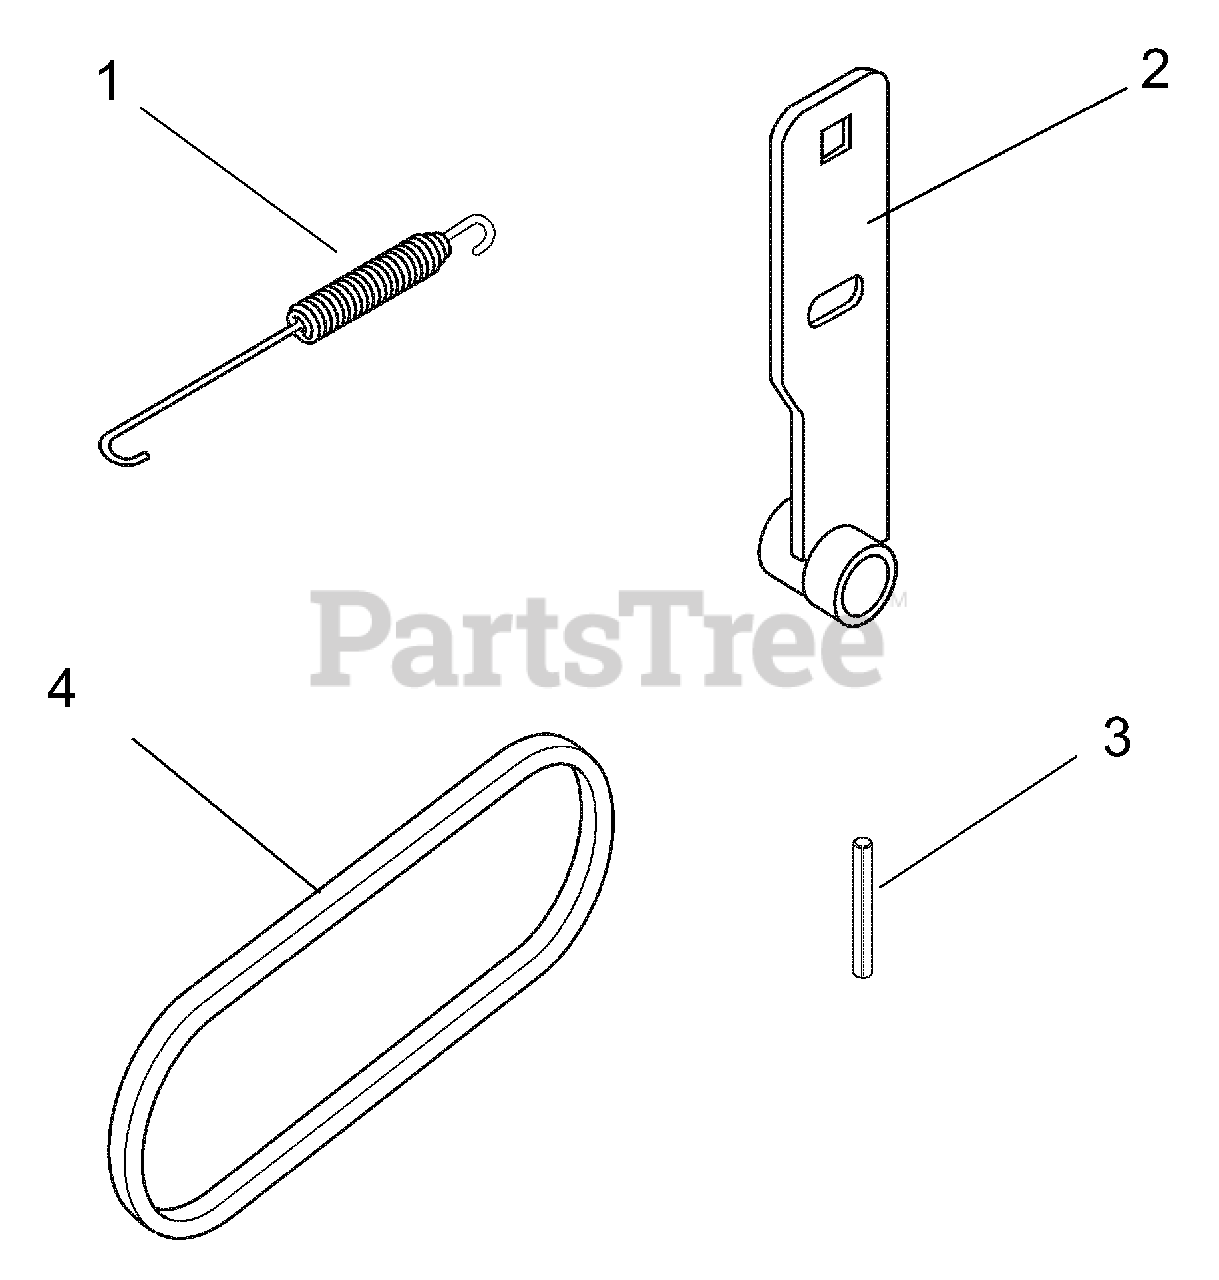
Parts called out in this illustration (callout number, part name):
1	KIT, BELT UPGRADE, 13HP
1	SG-TENS .06X.482X5.35
2	ARM, IDLER-TRACTION
3	DECAL, ATTACHMENT LOCKING PIN
4	V-BELT, 3L-WRAPPED
